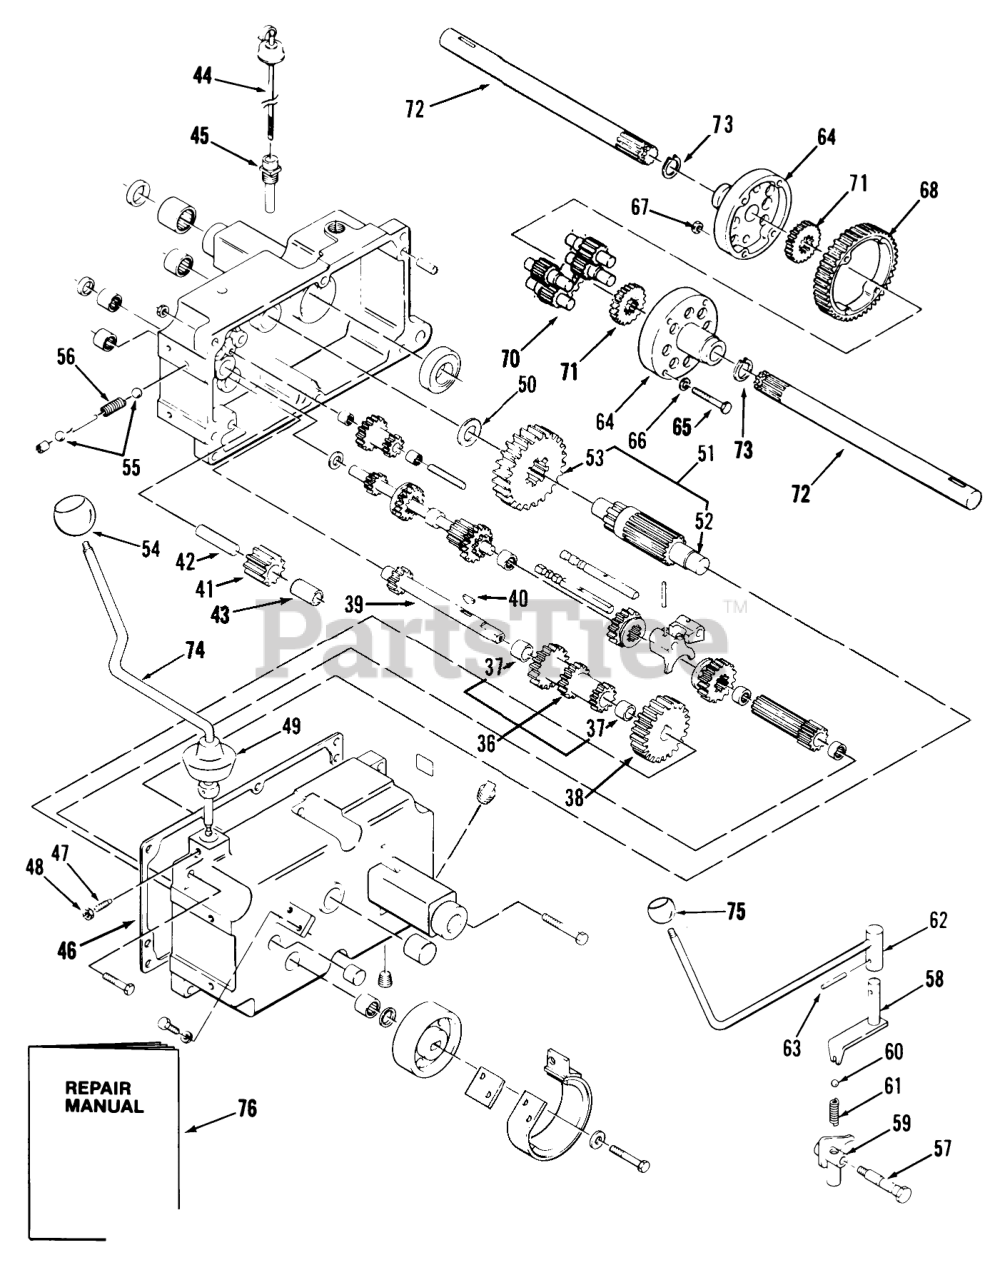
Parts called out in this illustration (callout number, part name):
36	GEAR-CLUSTER
37	BUSHING-BRONZE
38	GEAR-CLUSTER SHAFT
39	Cluster Shaft
40	KEY-WOODRUFF
41	GEAR/BUSHING ASM-REVERSE IDLER
42	PIN-DIFFERENTIAL
43	BUSHING
44	ASSY-DIPSTICK
45	NIPPLE-TRANS FILL
46	GASKET-TRANSMISSION
47	SETSCREW
48	Nut
49	COVER-DUST
50	WASHER-THRUST
51	GEAR ASM
52	PINION SHAFT
55	BALL-DETENT
56	SPRING-SHIFT STOP
57	BOLT-DETENT
58	SHIFT ASM
59	Shift Fork
60	BALL-DETENT
61	SPRING-SHIFT STOP
62	SHIFT ROD ASM
63	PIN-SPIROL
64	END CAP-DIFFERENTIAL
65	Bolt 3/8-16 x 3 1/4
65	BOLT-HEX
66	WASHER
68	DIFFERENTIAL BULL GR
68	GEAR-DIFFERENTIAL RING, 43T
70	GEAR-PINION, 11T
71	AXLE GEAR
71	GEAR-AXLE DIFFERENTIAL
72	AXLE-REAR
73	Snap Ring
73	RING-SNAP
74	ASM-Rod
75	Knob
76	MANUAL
